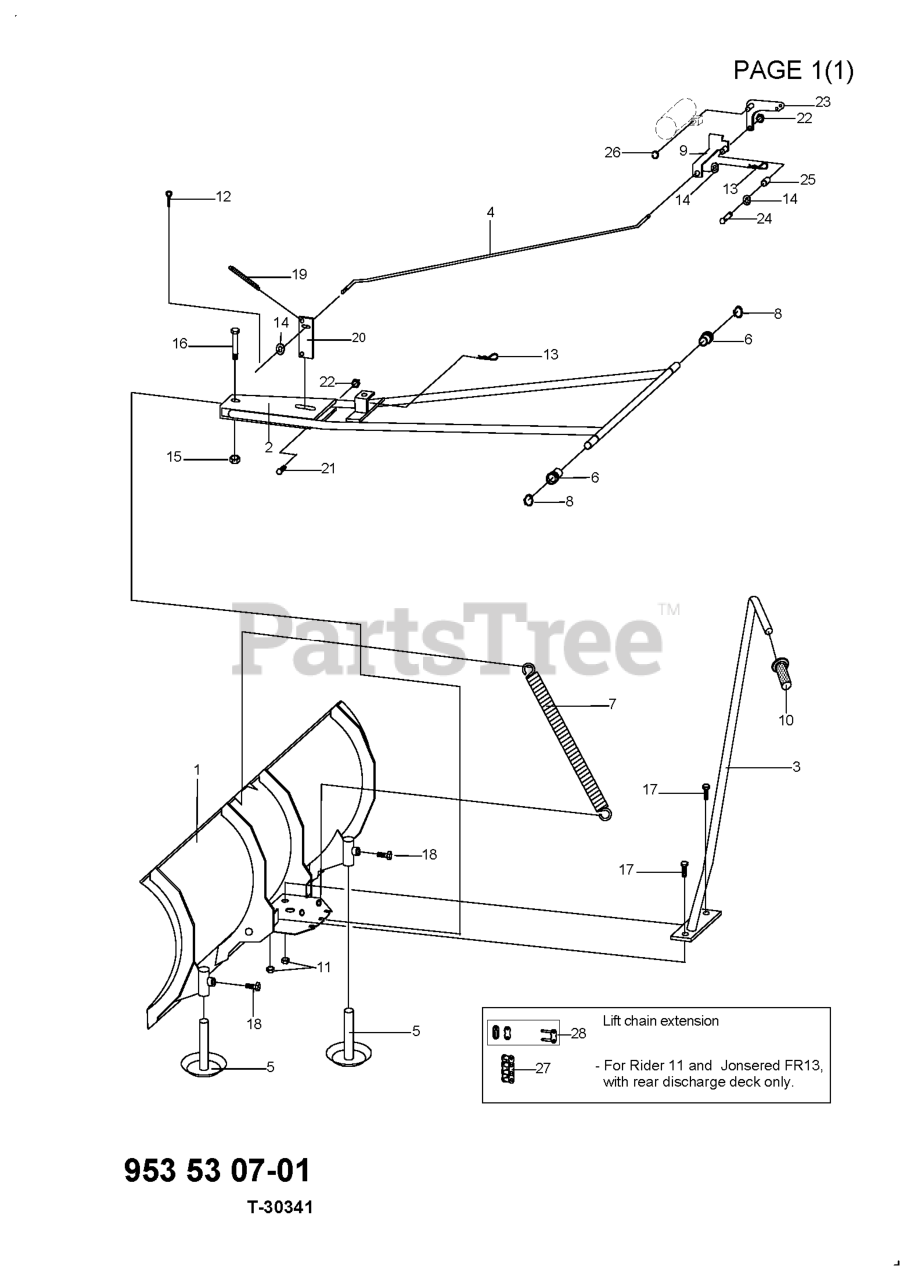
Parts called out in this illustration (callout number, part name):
5	SLIDING SHOE
12	PIN RETAINING SCREW
20	Plate, Lock
